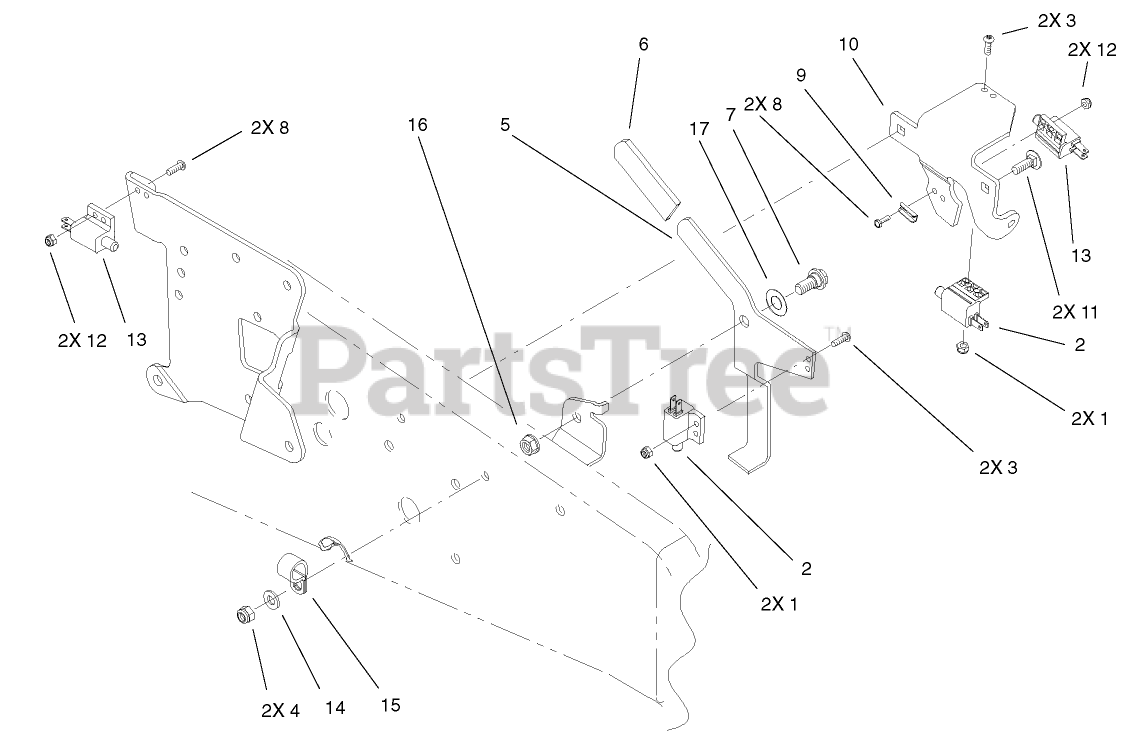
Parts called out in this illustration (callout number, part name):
1	NUT-LOCK, NI
3	SCREW-HSH
4	NUT-LOCK, NI
5	LATCH-BRAKE, PARKING
7	BOLT-SHOULDER
8	SCREW
9	RETAINER-SCREW
10	BRACKET-SWITCH
11	SCREW-CARR
12	NUT-LOCK
13	SWITCH-POLE, SINGLE
14	WASHER-PLAIN
15	CLAMP - R
16	NUT-HEX
17	WASHER
